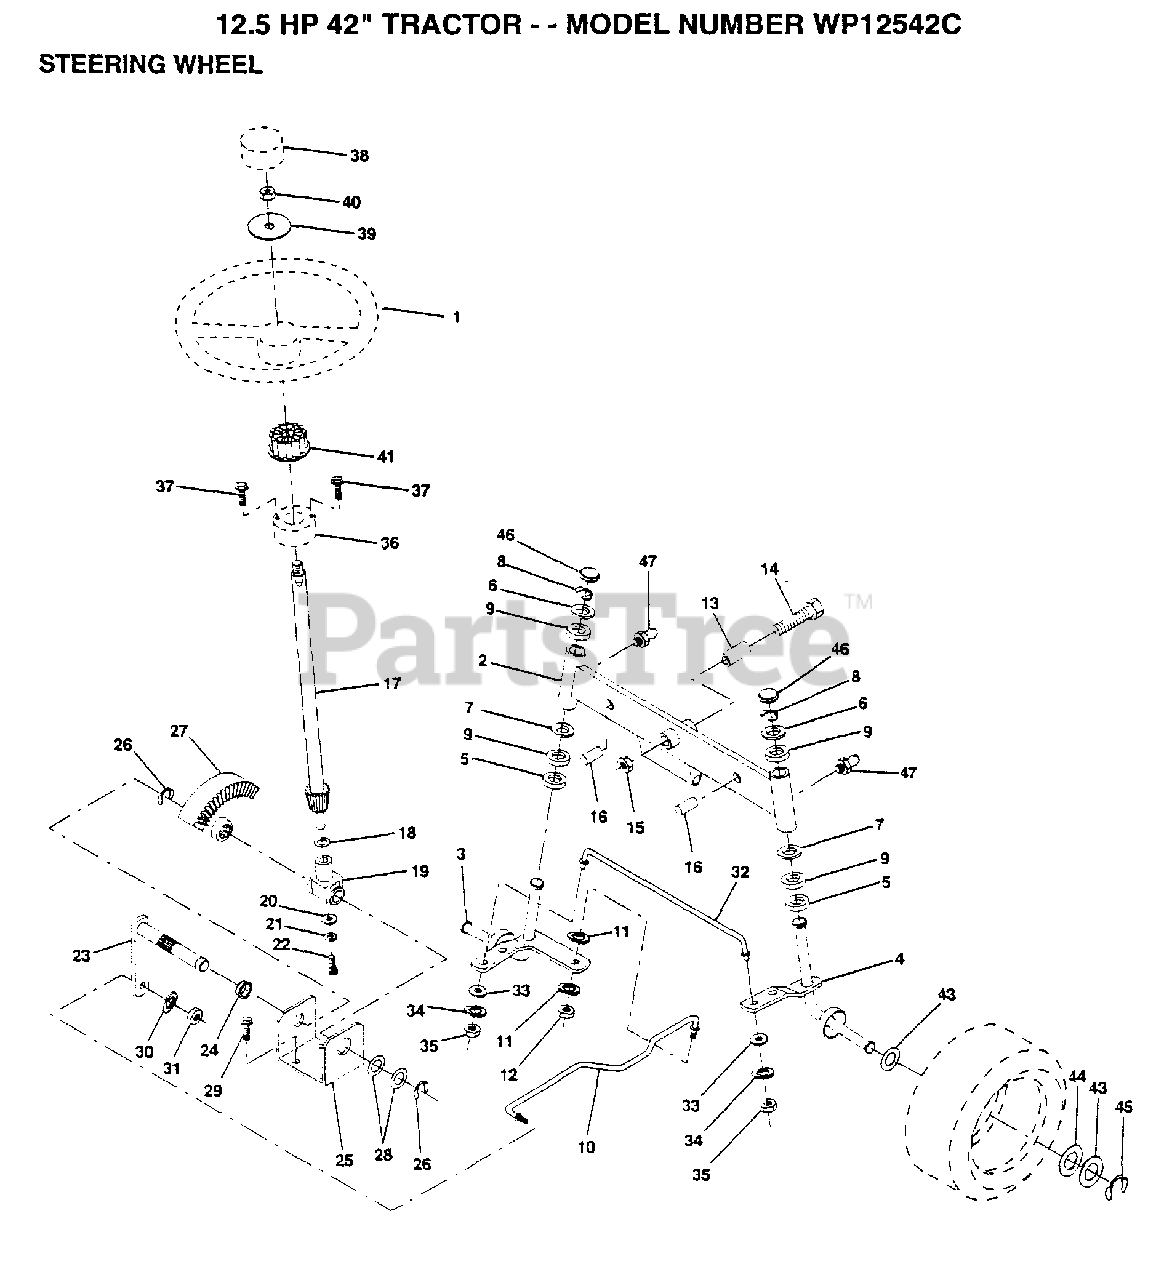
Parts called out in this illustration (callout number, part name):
2	AXLE ASM FRONT
3	SPINDLE LH
4	SPINDLE RH
5	WASHER .T
6	WASHER
7	WASHER
8	RING
9	COL. SRTG. BEAR.
11	LOCKWASHER
13	BEARING
14	BOLT HEX 5/8-11
15	"NUT-LOC,FLANGE LT"
16	AXLE PIN
17	STEERING SHAFT
18	THRUST WASHER
19	SUPPORT.SHAFT
21	LOCKWASHER
22	"SCREW,SPECIAL"
24	NYLINER T
25	"BRKT,STEERING"
26	RING
27	GEAR SECTOR
28	WASHER .T
29	SCREW
30	LOCKWASHER
32	TIE ROD
33	WASHER M
34	LOCKWASHER
35	NUT.LOCK.5/16-24
38	"INSERT,STR WHEEL"
39	WASHER
41	ADAPTER LT
43	WASHER
44	WASHER
45	RING
46	CAP
47	ZERK M
